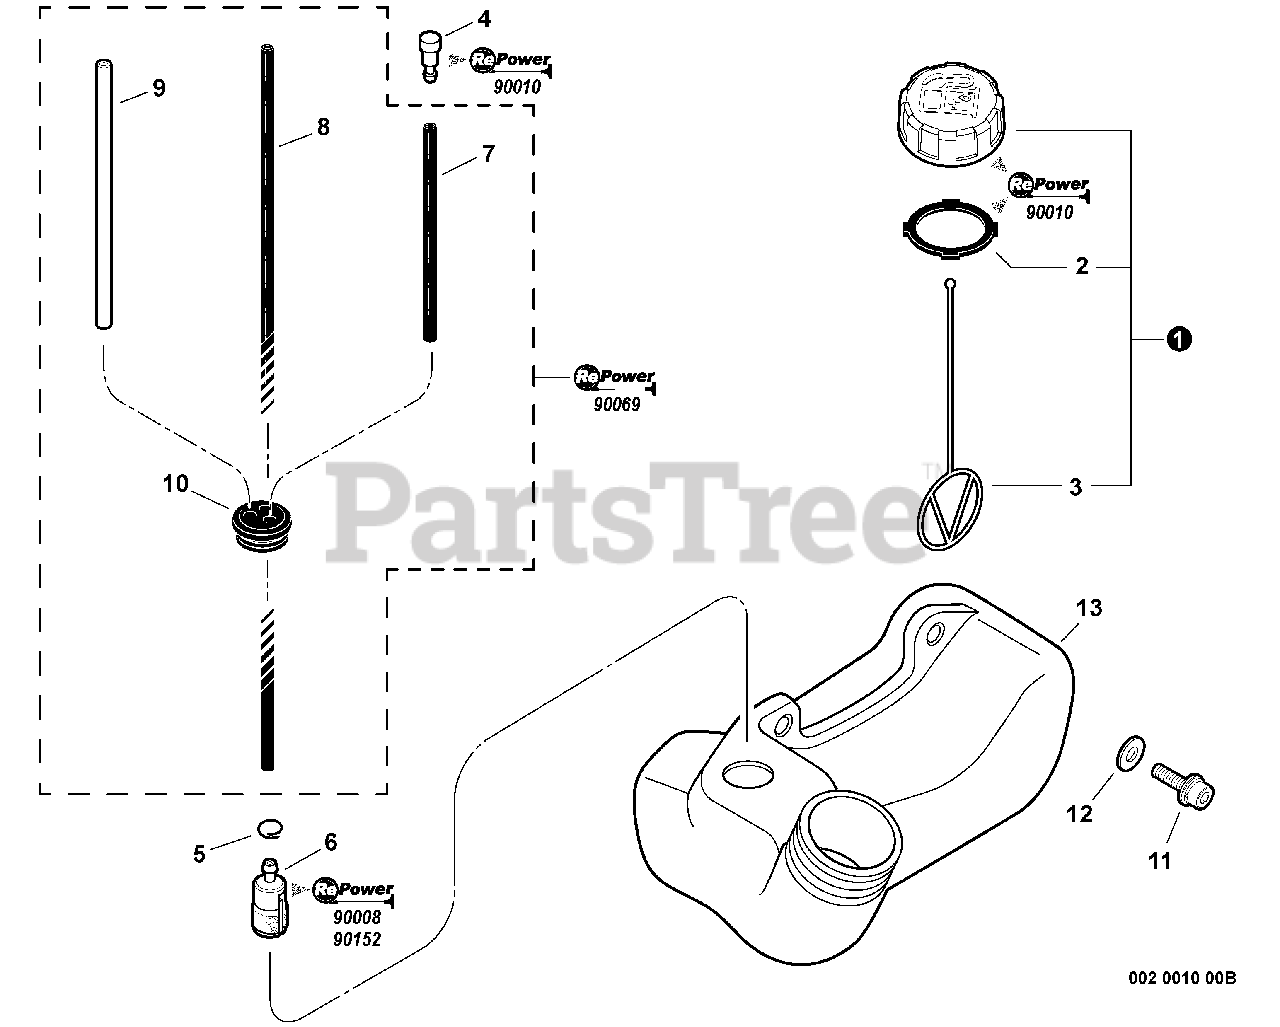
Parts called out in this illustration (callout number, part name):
1	CAP ASSY - ORANGE
2	GASKET, CAP
3	CONNECTOR, CAP
4	VENT, FUEL TANK
5	CLIP - 6
6	FILTER, FUEL
7	PIPE - 3X5X70 -- BLACK
8	PIPE - 3X5X180 -- BLACK
9	PIPE - 3X6X80 -- CLEAR
10	GROMMET
11	SCREW - 5X20
12	WASHER - 5
13	TANK, FUEL
14	RePower FILTER KIT
15	Repower CAP AND VENT KIT
16	RePower BULK PIPE - 25 FEET
17	RePower BULK PIPE - 25 FEET
18	Repower FUEL SYSTEM KIT
19	Repower TUNE-UP KIT
